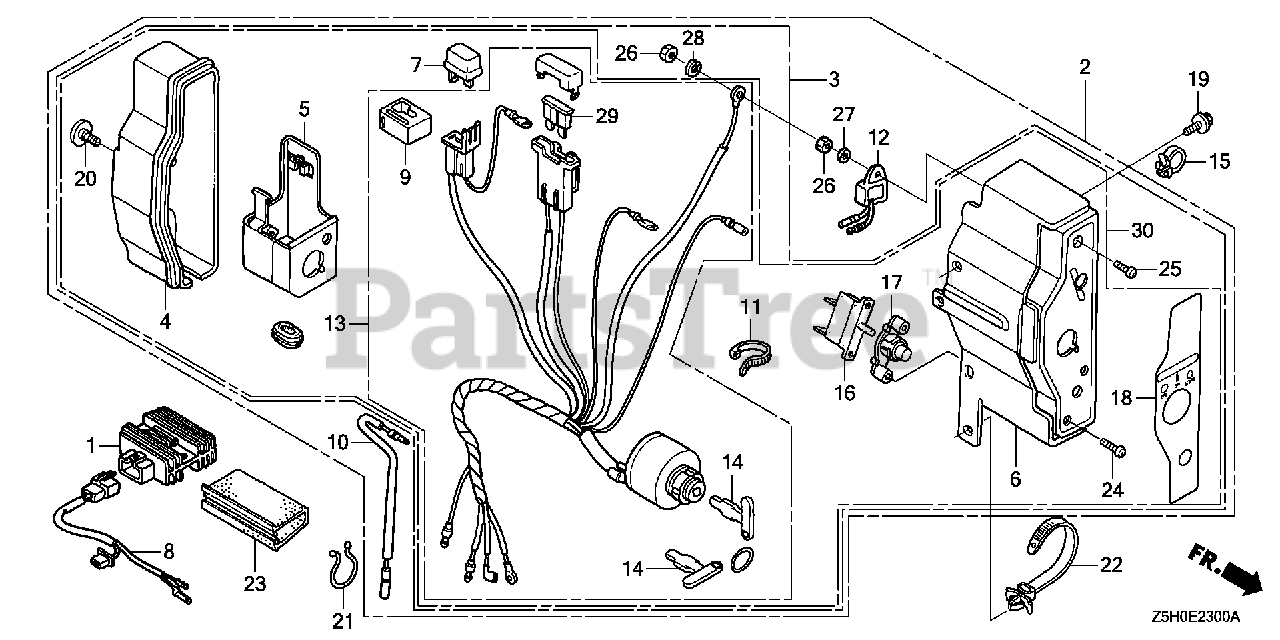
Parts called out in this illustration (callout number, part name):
4	CASE, CONTROL
5	BRACKET, CASE MOUNTING
6	PANEL, CONTROL *R280* (POWER RED)
7	RECTIFIER ASSY., SILICON (SHINDENGEN)
9	SUSPENSION, CONNECTOR
11	BAND
13	SWITCH ASSY., COMBINATION
14	KEY
15	HOLDER, STOP SWITCH WIRE Use up to Engine SN 2056819.
16	PROTECTOR, CIRCUIT (1.0A)
17	LENS ASSY., PROTECTOR
18	MARK, CONTROL BOX (EXTERNAL)
19	BOLT, FLANGE (6X12) (CT200)
20	SCREW, SPECIAL (6X12)
21	CLIP, PURSE LOCK
22	STRAP, CABLE (118MM) *NH1L* (Honda Code 1170653). (BLACK)
23	TUBE, FASTENER (30)
24	SCREW, PAN (3X12)
29	FUSE, BLADE (5A)
30	BOX ASSY., CONTROL *R280* (EXP-ALERT) (POWER RED)
